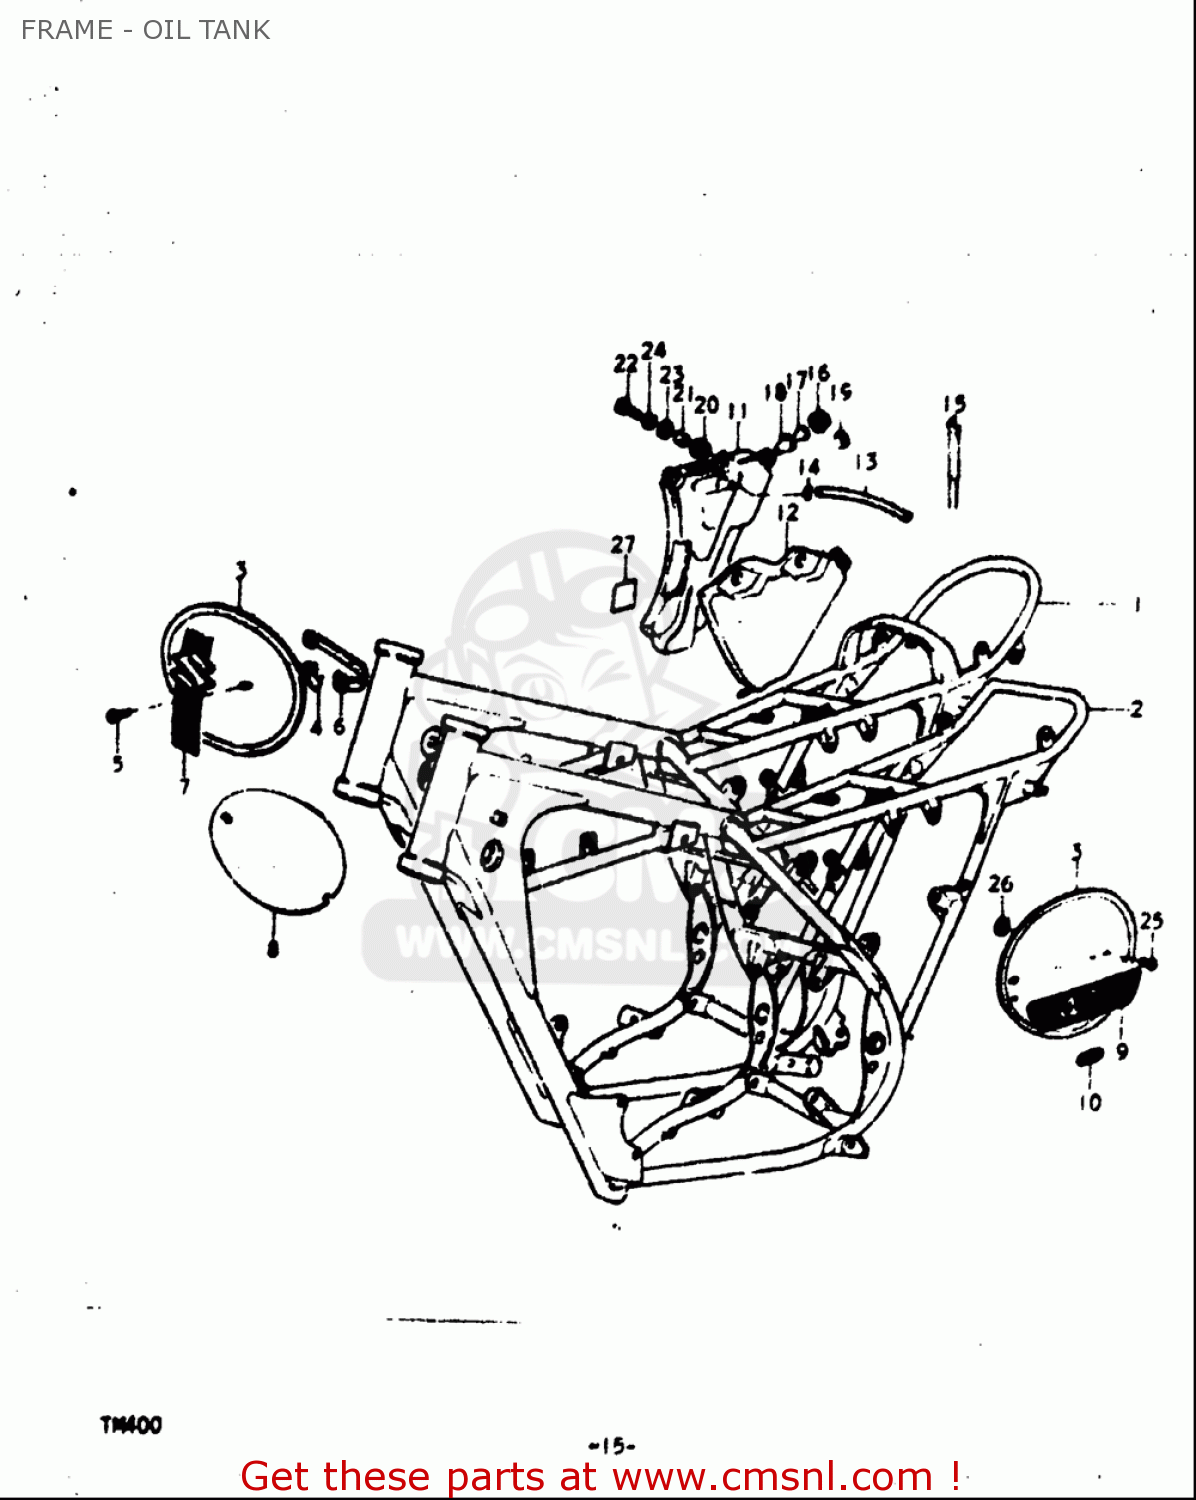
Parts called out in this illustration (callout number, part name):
5	SCREW 6X12
6	BAND
10	EMBLEM,CCIS
13	HOSE(5X8X2000)
14	CLIP
15	CLAMP
16	CAP, OIL TANK
17	GASKET,OIL TANK CAP (NAS)
18	GASKET,OIL TANK CAP (NAS)
19	GASKET,OIL TANK CAP (NAS)
20	CUSHION
21	SPACER(6.5X10X10)
22	BOLT
23	WASHER(6.5X20X1.2)
24	WASHER,LOCK
25	BOLT
26	WASHER
